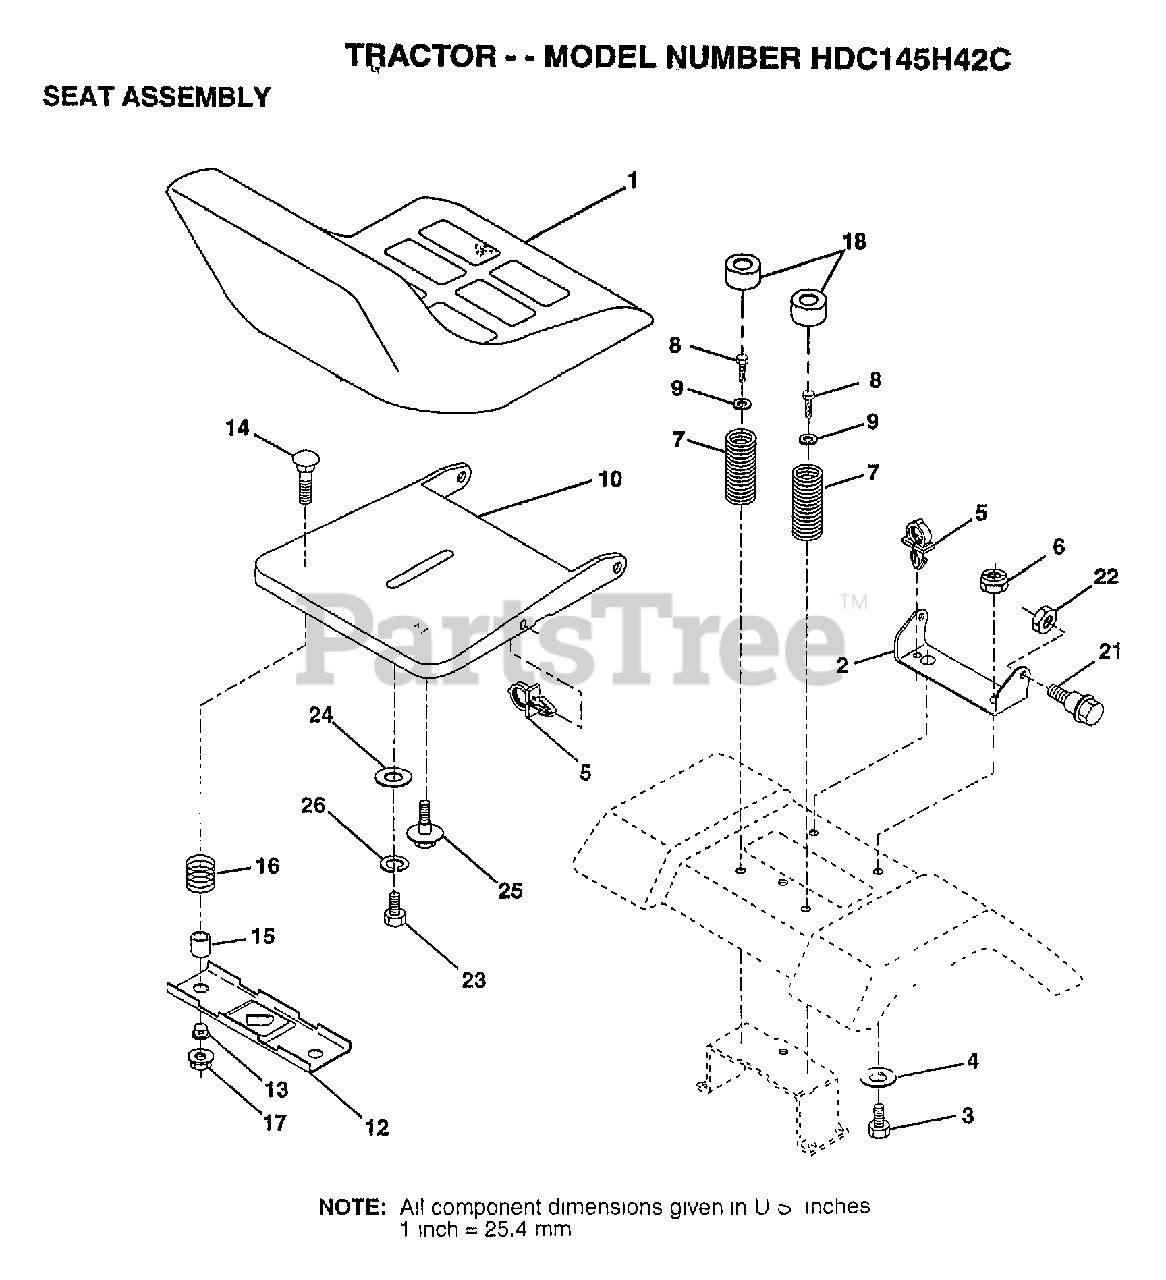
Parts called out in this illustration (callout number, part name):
1	SEAT
2	BRACKET PVT SEAT
3	BOLT
4	WASHER PM
5	CLIP.PUSH-IN.HING
6	NUT
7	SPRING COMPRESSIO
8	SCREW GTV
9	WASHER
10	PAN-SEAT
12	BRKT SWITCH
13	BUSHING
15	SPLIT SPACER
16	SPRING
18	CAP SPRING
21	"BOLT,SHOULDER"
23	BOLT
24	WASHER
25	"BOLT,SHOULDER"
26	LOCKWASHER
